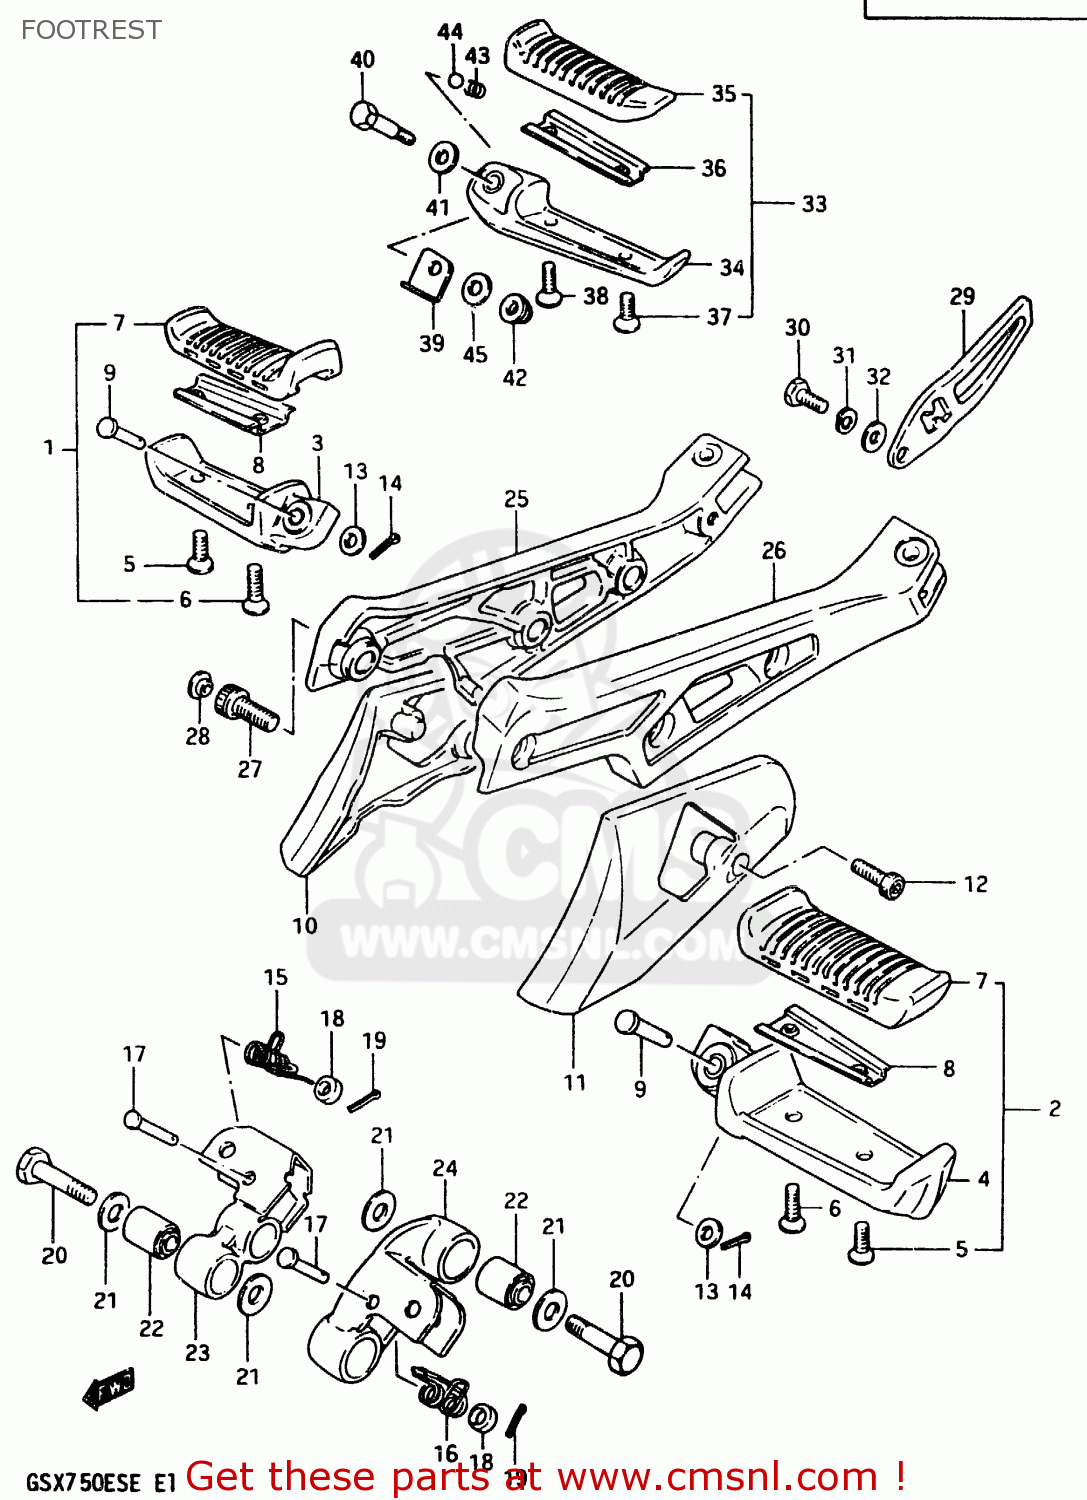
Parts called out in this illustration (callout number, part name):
1	FOOTREST ASSEMBLY,FRONT,RIGHT
2	FOOTREST ASSEMBLY,FRONT,LEFT
3	BAR,FRONT FOOTREST,RIGHT
4	BAR,FR FOOTREST,L
5	SCREW
6	SCREW
7	RUBBER,FOOTREST
8	PLATE,FR FOOTREST RUBBER
9	PIN
10	COVER,FRONT FOOTREST,RIGHT
11	COVER,FRONT FOOTREST,LEFT
12	BOLT
13	WASHER,8.5X16X
14	PIN 20X20
15	SPRING
16	SPRING
17	PIN
18	SPACER (6.5X12X5.5)
19	PIN 20X20
20	BOLT 10X40
21	WASHER(10.5X20X3.2)
22	BUSH
23	HOLDER,FRONT FOOTREST,RIGHT
24	HOLDER,FRONT FOOTREST,LEFT
25	BRACKET,MUFFLER,RIGHT
26	BRACKET,MUFFLER,LEFT
27	BOLT
28	CAP
29	GUARD,REAR FOOT
30	BOLT
31	LOCK WASHER
32	WASHER
33	FOOTREST ASSY,PILLION,R
34	BAR,PILLION FOOTREST,LEFT
35	RUBBER,RR FOOTREST
36	PLATE,RUBBER STOPPER
37	SCREW 5X12
38	SCREW 5X16
39	PLATE,SPRING STOP
40	BOLT
41	WASHER
42	NUT
43	SPRING
44	BALL
45	SHIM(8.2X22X0.2)
